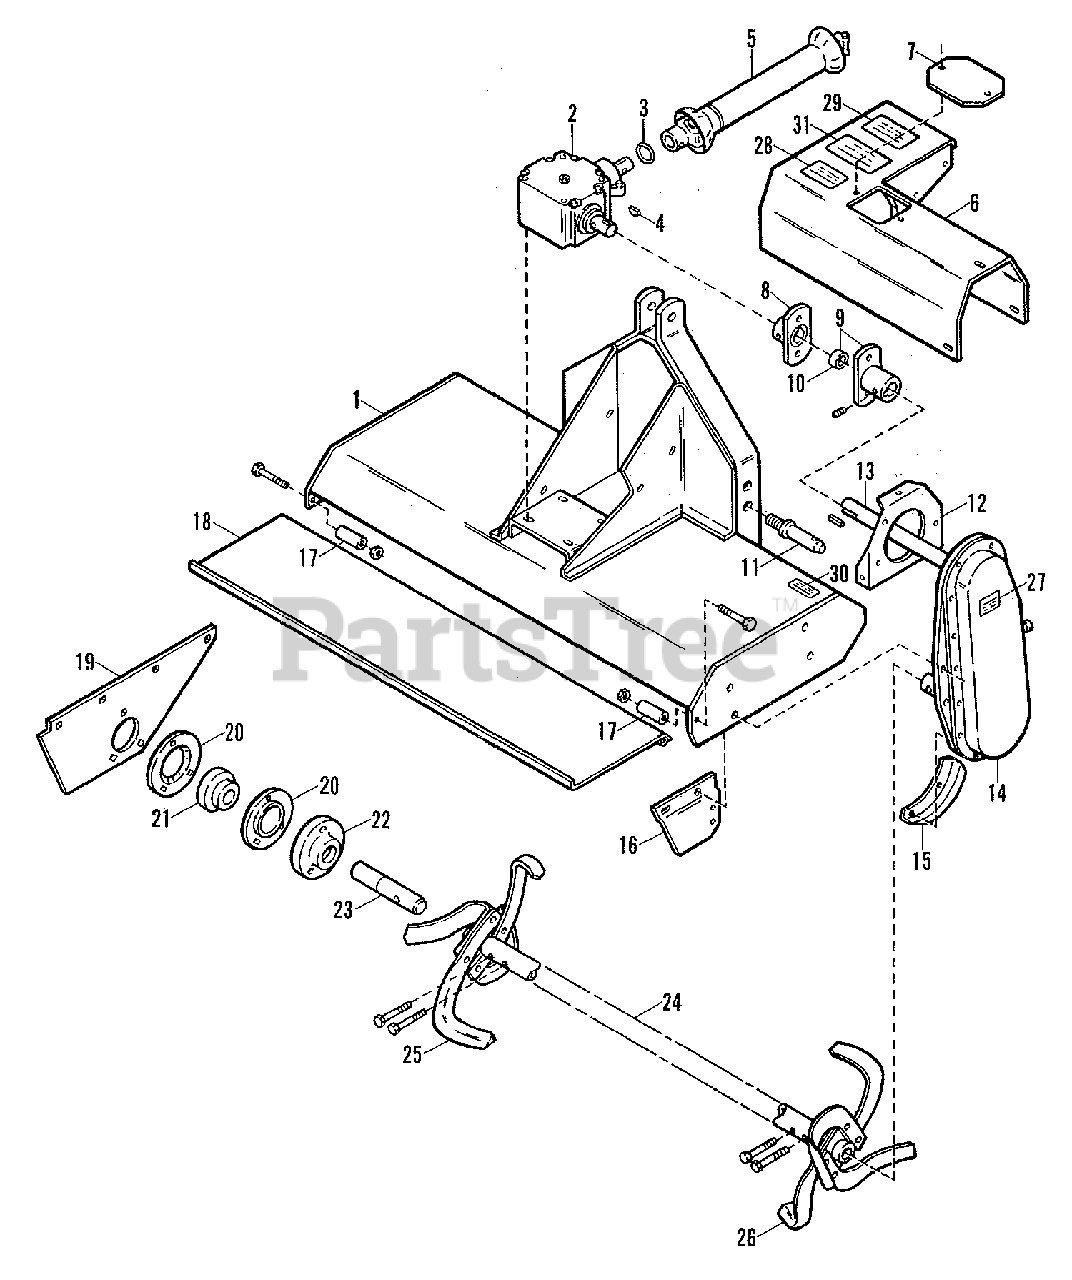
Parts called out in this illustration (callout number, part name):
1	HOUSING, Tiller
2	GEARBOX ASSEMBLY, Complete
2	CAPSCREW, 3/8NC x 1
2	WASHER, Plain, 3/8 x 1 x 12 Ga.
2	LOCKWASHER, 3/8
3	RING, Retaining
4	KEY, Woodruff, 1/4 x 1
5	UNIVERSAL ASSEMBLY, Complete
5	CAPSCREW, Socket Head, 5/16NC x 2, Gr. 8
5	NUT, Lock, 5/16nc
6	SHIELD, Drive
6	CAPSCREW, 5/16NC x 3/4
6	CAPSCREW, 5/16NC x 1/2
6	LOCKWASHER, 5/16
6	WASHER, Plain, 5/16 x 3/4 x 14 Ga.
7	PLATE, Inspection Cover
7	CAPSCREW, 5/16NC x 1/2
7	LOCKWSHER, 5/16
8	FLANGE, Shear Plate
8	CAPSCREW, 1/4NC x 1-1/2
8	LOCKWASHER, 1/4
8	CAPSCREW, Socket Head, 5/16NC x 2, Gr. 8
8	NUT, Lock, 5/16NC
9	FLANGE, Shear Plate
9	SETSCREW, Square Head, Cup Point, 3/8NC x 1
10	BUSHING, Flange
11	LOCKWASHER, 7/8
12	PLATE, End, Drive Shield
13	SHAFT, Input
13	KEY, Woodruff, 5/16 Square x 2
14	CHAINCASE ASSEMBLY
14	CAPSCREW, 5/16NC x 1
14	LOCKWASHER, 5/16
14	NUT, 5/16NC
14	CAPSCREW, 1/2NC x 1-1/4
14	LOCKWASHER, 1/2
16	DEFLECTOR, Spill
17	BUSHING, Hinge
17	CAPSCREW, 3/8NC x 3
17	NUT, Lock, 3/8NC
18	SHIELD, Rear
19	PLATE, Mounting, L.H.
19	BOLT, Carriage, 3/8NC x 1
19	LOCKWASHER, 3/8
20	FLANGE, Bearing
20	BOLT, Carriage, 3/8NC x 1-1/2
20	LOCKWASHER, 3/8
22	COVER, Dust Excluder
23	SHAFT, Support
24	TUBE, Tine Mounting
24	CAPSCREW, 1/2NC x 3
24	NUT, Lock, 1/2NC
25	CAPSCREW, 7/16NF x 1-1/2
25	NUT, Crown Lock, 7/16NF
26	CAPSCREW, 7/16NF x 1-1/2
26	NUT, Crown Lock, 7/16NF
27	DECAL, Caution (Stand Clar)
28	DECAL, Warning (Shields)
29	DECAL, Warning (P.T.O.)
30	DECAL, Warning
31	DECAL, Notice (Shear Pin)
